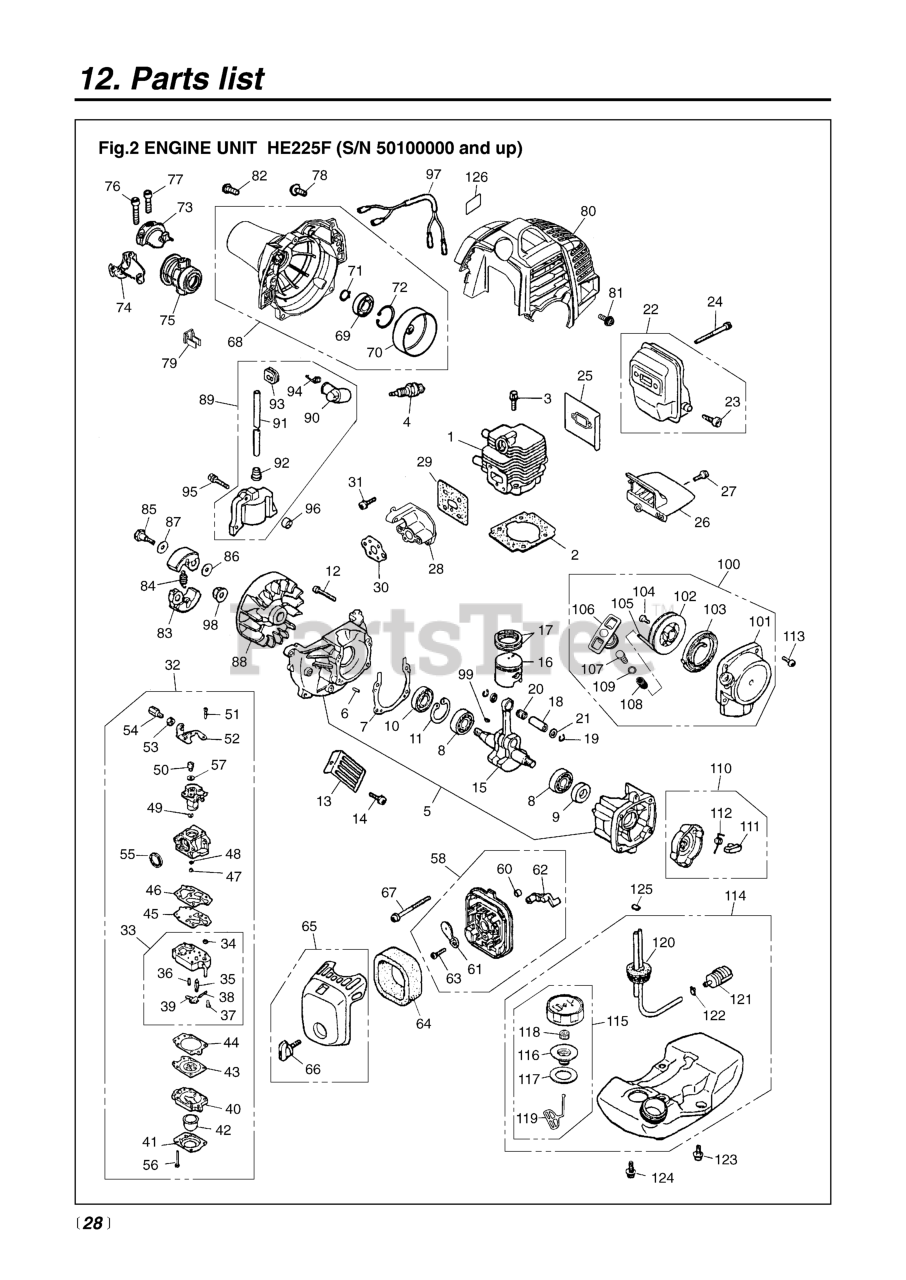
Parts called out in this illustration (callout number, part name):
1	CYLINDER
2	GASKET, BASE (RPLS -12212)
3	BOLT, M5 X 22
4	PLUG, SPARK (RPLS 5602-73110)
5	CRANKCASE
6	PIN
7	GASKET (RPLS -21140)
8	BEARING
9	SEAL, OIL (RPLS 1100-21210)
10	SEAL, OIL (RPLS 1140-21220)
11	RING, SNAP, M28 x 1.2
12	BOLT, M5 X 30
14	SCREW,M5 X 14 (RPLS 1400-15510
15	CRANKSHAFT (RPLS 1850-42000)
16	PISTON (REPLACES 1140-41110)
17	RING, PISTON (RPLS 1850-41210)
18	PIN, PISTON 5x8x26
19	RING, SNAP (RPLS 1101-41320)
20	BEARING (RPLS 1140-41330)
21	WASHER
22	MUFFER ASSEMBLY
23	ARRESTER (RPLS 5850-15140)
24	BOLT, M5 x 50
25	GASKET
26	PLATE, MUFFLER (RPLS -15220)
27	SCREW, M4 X 16
28	INSULATOR
29	GASKET (RPLS -13120)
30	GASKET (REPLACES -13130)
31	SCREW, M5X20 (RPLS.1400-75510)
32	CARBURETOR
33	BODY, PUMP
35	VALVE, INLET
36	SPRING, METERING LEVER
37	SCREW, METERING LEVER PIN
38	PIN, METERING LEVER
39	LEVER
40	BODY, PURGE
41	COVER, PUMP
42	PUMP, PRIMING
43	DIAPHRAGM (USE 4810-81260)
44	GASKET, DIAPHRAGM
45	DIAPHRAGM
46	GASKET, PUMP
47	JET
48	RING, O
49	RING
50	SWIVEL
51	SCREW
53	NUT, CABLE ADJUSTER
54	SCREW, CABLE ADJUSTER
55	RING, PACKING
56	SCREW
57	WASHER
58	BODY ASSEMBLY
60	SLEEVE
61	PLATE, CHOKE
62	LEVER, CHOKE
63	SCREW (REPLACES 50030272)
64	ELEMENT
65	COVER ASSEMBLY
66	KNOB (RPLS -82220)
67	SCREW, M5 x 60
68	HOUSING ASSY
69	BEARING
70	DRUM, CLUTCH
71	RING, SNAP (RPLS 3130-13270)
72	RING, SNAP, M28 x 1.2
73	BRACKET (A) (RPLS -31211)
74	BRACKET (B)
75	CUSHION (RPLS -31231)
76	BOLT, M5 X 22
77	BOLT, M5 X 10
78	SCREW, M5X20 (RPLS.1400-75510)
79	CLAMP
80	COVER, ENGINE (RPLS. -32110)
81	SCREW (RPLS-32161)
82	SCREW,M5 X 14 (RPLS 1400-15510
83	SHOE
84	SPRING
85	BOLT
86	WASHER, FLAT (USE 182303)
88	ROTOR
89	COIL-A (REPLACES -71200)
90	CAP
91	CORD
92	CAP
93	GROMMET
94	SPRING
95	BOLT
96	SPACER
97	CORD COMP
99	KEY
100	RECOIL ASSEMBLY
101	CASE
102	REEL
103	SPRING, SPIRAL
104	SCREW (RPLS -75150)
105	ROPE
106	KNOB
107	COLLAR
108	SPRING
109	WASHER
110	PULLEY ASSY (RPLS -75210)
111	RATCHET (RPLS 1850-75220)
112	SPRING, RETURN
113	SCREW (RPLS-32161)
114	TANK ASSY (RPLS -85000)
115	CAP ASSY (RPLS. 5601-85201)
116	HOLDER - A (RPLS 5601-85230)
117	PACKING
118	FILTER
119	STOPPER
120	PIPE COMPLETE
121	FILTER (RPLS 1850-85300)
122	CLIP (REPLACES 2841-31280)
123	SCREW W/ WASHER
124	SCREW
125	CLIP
126	LABEL
